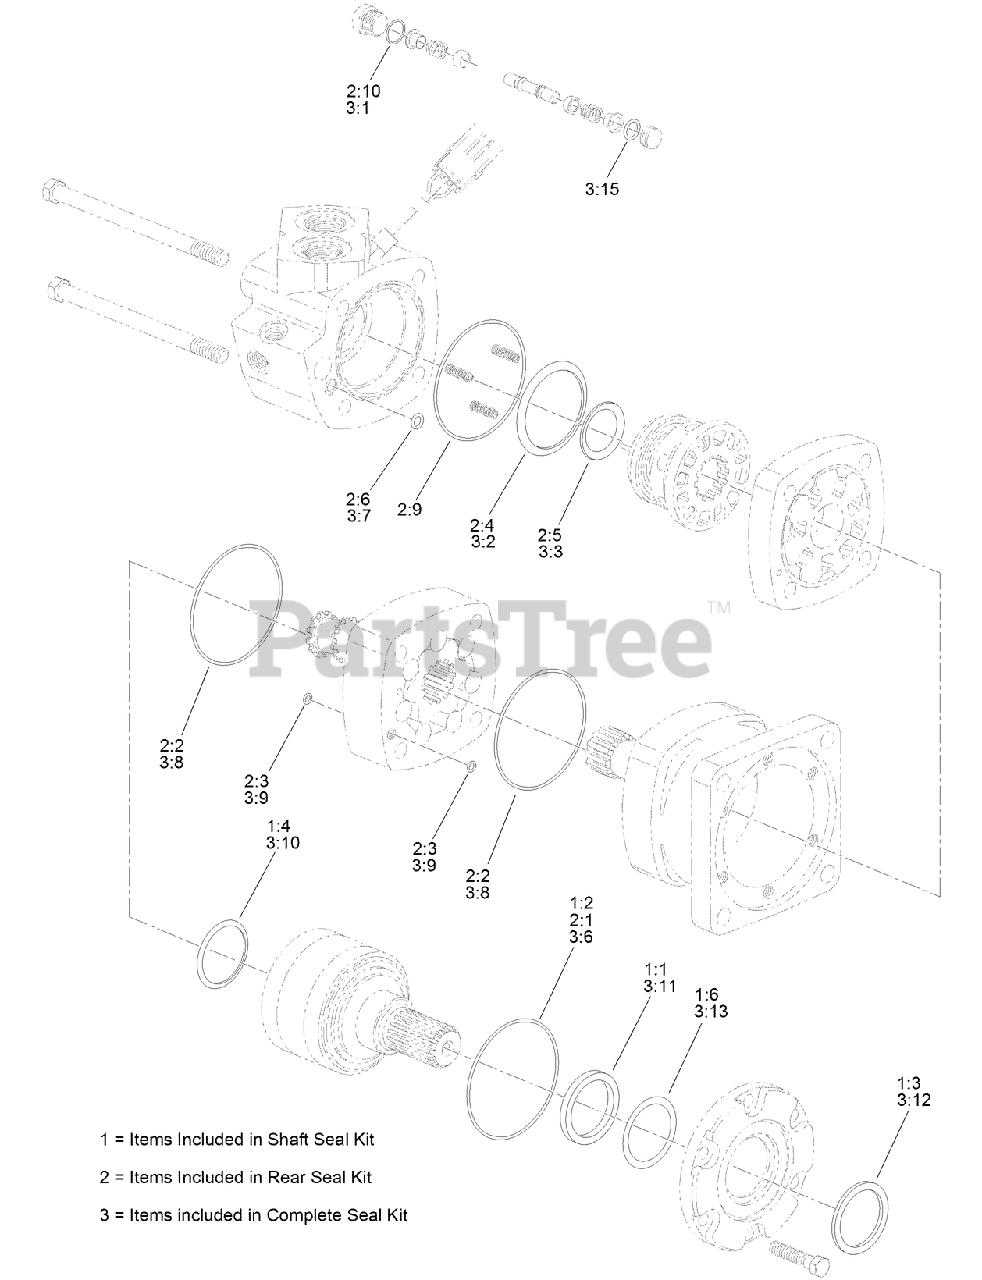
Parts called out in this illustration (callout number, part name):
1	SEAL KIT
1:1	SEAL
1:2	O-RING
1:3	SEAL-DUST
1:4	Seal-Face, Shaft
1:6	RING-BACKUP
2	SEAL KIT
2:1	O-RING
2:2	O-RING
2:3	O-RING
2:4	Seal-Face, Outer
2:5	Seal-Face, Inner
2:6	O-RING
2:9	SEAL
2:10	O-RING
3	SEAL KIT
3:1	O-RING
3:2	Seal-Face, Outer
3:3	Seal-Face, Inner
3:6	O-RING
3:7	O-RING
3:8	O-RING
3:9	O-RING
3:10	Seal-Shaft Face
3:11	SEAL
3:12	SEAL-DUST
3:13	RING-BACKUP
3:15	O-RING
